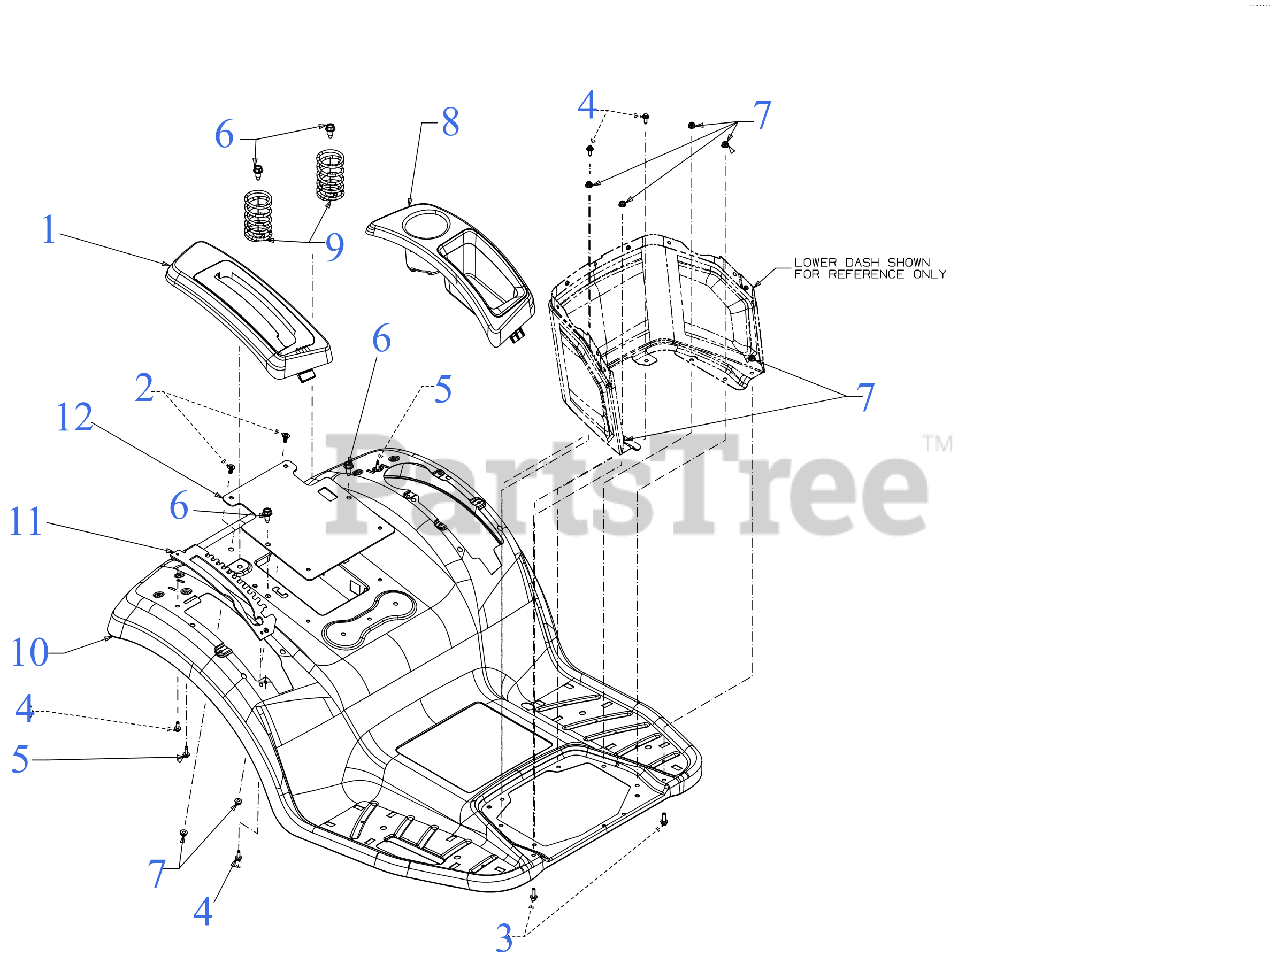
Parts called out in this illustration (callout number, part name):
1	FENDER COVER (RH)
2	CARRIAGE BOLT 1/4-20 x .62
3	SCREW 1/4-20 x .75 GR5
4	SCREW M6-1 x .625
5	SCREW 1/4-10 x .750
6	HEX SCREW WASH TT 3/8-16 x .875
7	FLANGE LOCK NUT
8	FENDER COVER (LH)
9	COMPRESSION SPRING 2.18 x 3.65 x .207
12	FENDER COVER PLATE
